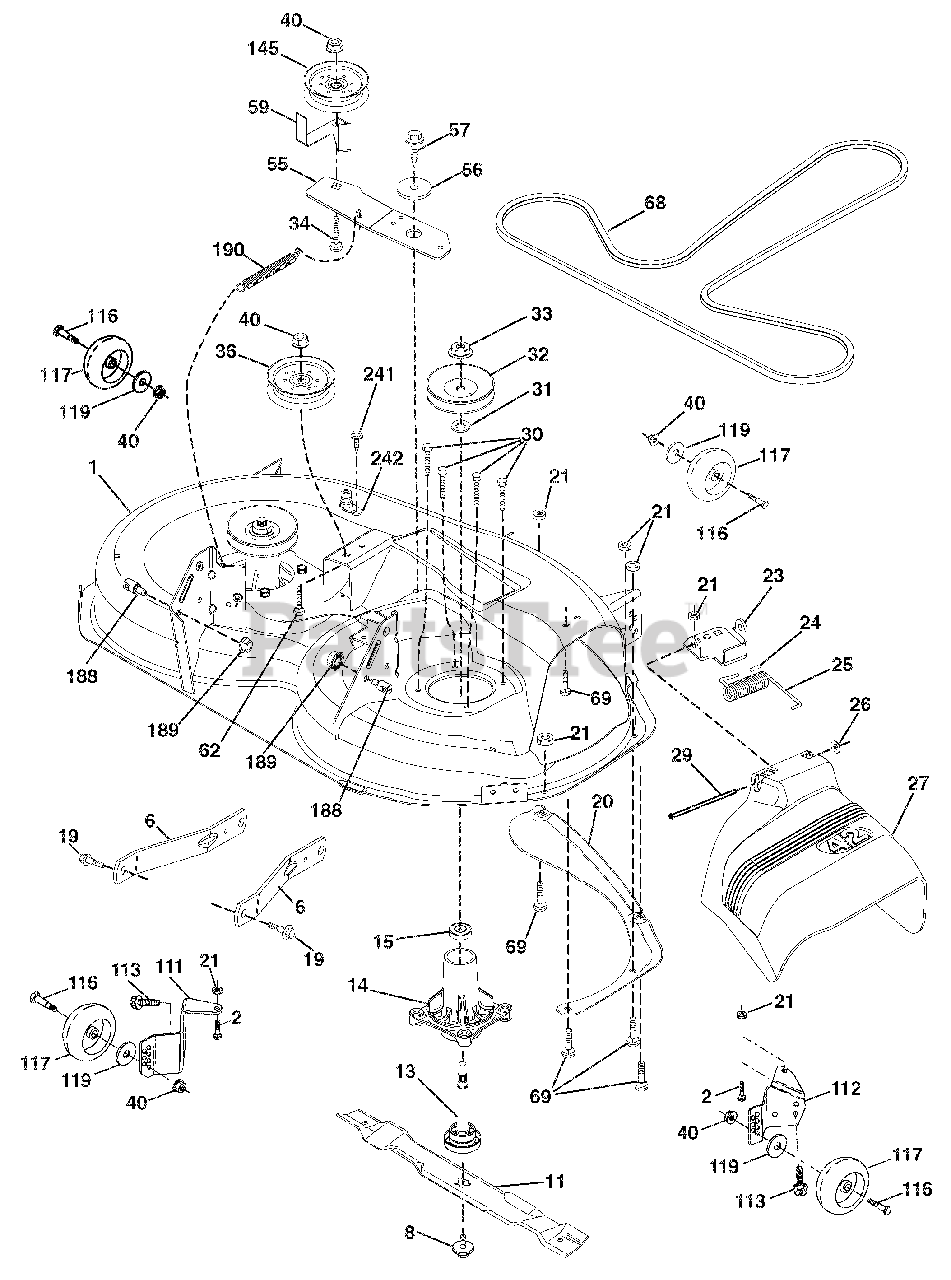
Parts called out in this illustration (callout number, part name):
1	MOWER HOUSING
6	ARM.SUSPENSION.MOWER.REAR.LD
8	BOLT/WASHER ASM.7/16-20.UNF
11	BLADE.MOWER.42"HI LIFT PREMIUM
13	SHAFT ASM.MNDRL.N/GREASEABLE38
14	HOUSING.MANDREL.4PT.SERVICE
15	BEARING.BALL.MANDREL
19	BOLT.SHOULDER
20	BAFFLE.VORTEX.42.STD/HEAVY DTY
21	Nut, Hex, Crownlock 5/16-18
23	BRACKET.DEFLECTOR.38/42"2005
24	CAP.SLEEVE..80X.112.BLK.MOWER
25	SPRING.TORSION.DFL.38/42/46.GR
26	NUT.PUSH.PHOS.& OIL
27	SHIELD.DEFLECTOR.
29	ROD.HINGE.42/46"
30	SCREW.THD ROLL.DOD PT.HEX
31	WASHER.SPACER.MANDREL
32	MANDREL.PULLEYS.42,44,50
33	NUT.FLANGE.LOCK.TOP
34	BOLT.CARR.SH.3/8-16X1-1/2.GR5
36	PULLEY.IDLER.4.50.RAW
40	Nut, Hex, Flangelock 3/8-16
55	IDLER.ARM
56	SPACER.RETAINER
57	SCREW.3/8-16X1.SMGML.TAP/R.BLK
59	GUARD.TUV.IDLER
62	BOLT.RD.HD.SQ.NK.3/8-16UNC X 2
68	V-Belt, 42" Mower
69	BOLT.RDHD.SQNK.5/16-18 X 5/8
111	BRACKET WHEEL GAUGE LH
112	BRACKET WHEEL GAUGE RH
113	BOLT.5/16-18HEX.WHS.HD.LCKSERR
116	BOLD SHLD "A" 2.41 "B" 1.66
117	WHEEL.GAGE.HALF.SPOKED
119	Washer 3/8 x 7/8 x 14 Ga.
145	PULLEY.IDLER 48"PRIMARY
188	STUD.FASTNER.W/'D'ANTI-ROTATIO
189	Nut, Lock Hex Flange 5/16-18 u
242	PORT WASHOUT
